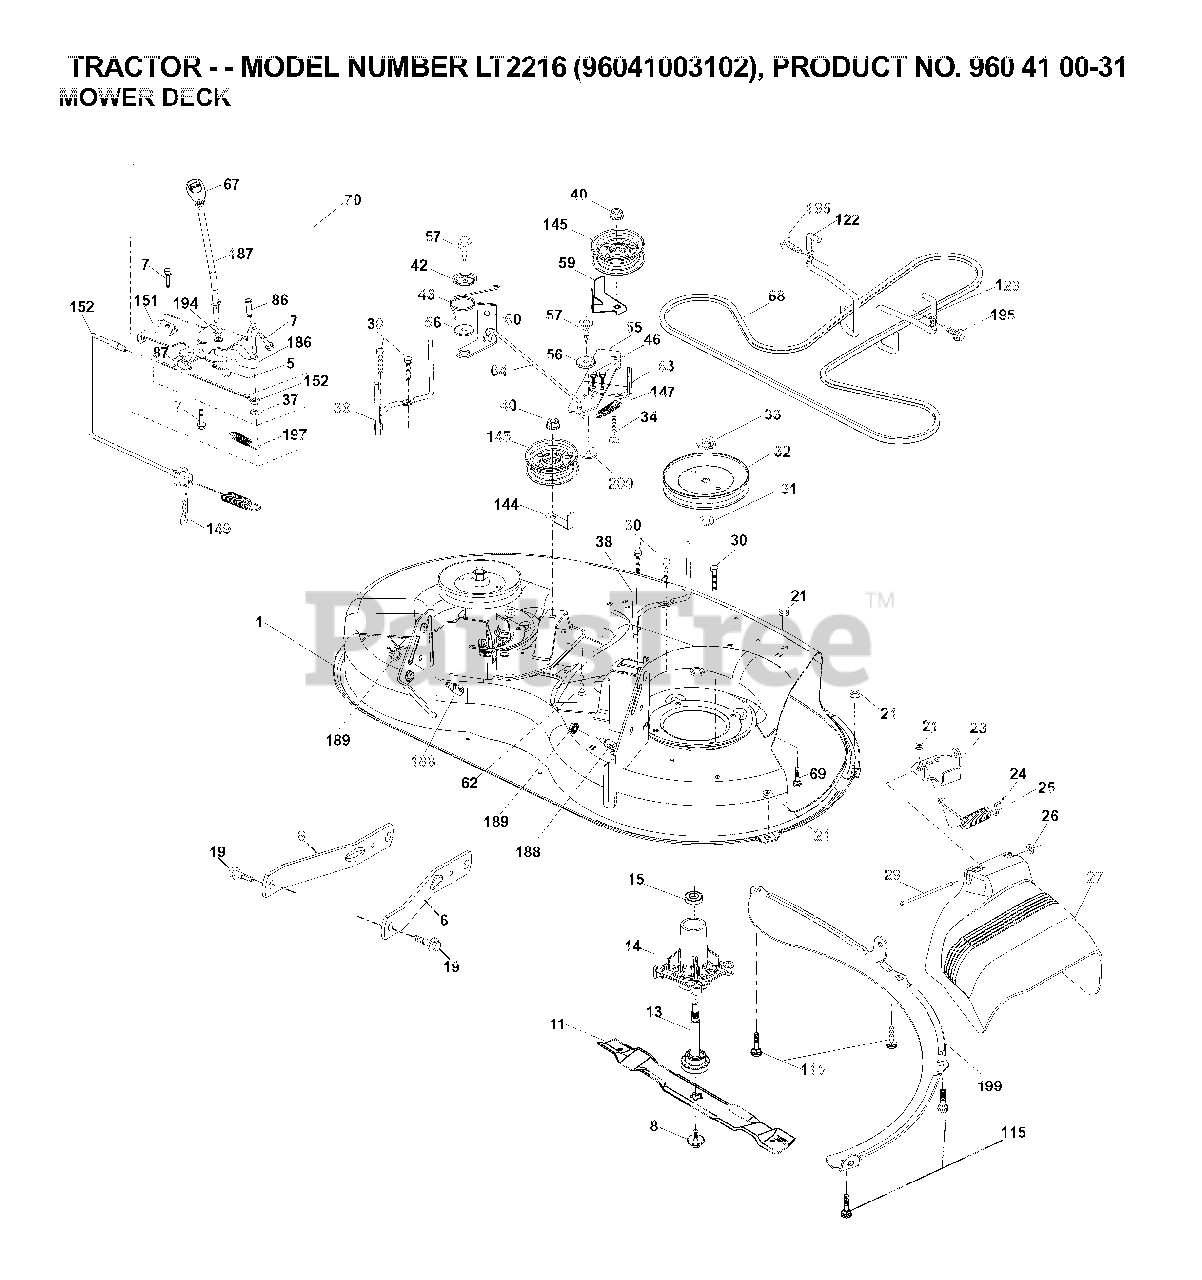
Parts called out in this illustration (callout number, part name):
6	ARM.SUSPENSION.MOWER.R
7	SCREW.#10 X 0.750.BOS THREAD
8	BOLT.WASHER.ASM.7/16-2
11	BLADE 38" PREMIUM
13	SHAFT.ASM.MDRL.N/GREASE.38
14	HOUSING MANDREL
19	BOLT.SHOULDER
21	LOCKNUT
23	BRKT.DEFLECTOR.38"2005+
24	CAP-SLEEVE LT
25	SPRING.TORSION.DEFLECT
26	NUT PUSH M
29	ROD.HINGE
30	SCREW, WASHER HEAD
31	WASHER.SPACER.MANDREL
32	PULLEY.MANDREL.5.0.PD.38"
33	NUT.FLANGE.LOCK.TOP
34	BOLT.3/8-16X1.50
38	KEEPER BELT LH MANDREL
40	NUT LOCK FLG 3/8-16 UNC
42	SPRING.TORSION.BRAKE
43	SRPING.TORSION.RETAINE
46	SCREW.1/4-20X5/8
55	IDLER.ARM
56	SPACER.RETAINER
57	SCREW 3/8-16X1
59	GUARD, BELT
60	ARM BRAKE MOWER RH 38"
62	BOLT.3/8-16X1.50
63	ARM BRAKE MOWER RH
64	LINK BRAKE
67	HANDLE.CLUTCH.CABLE.LT
69	BOLT
70	CLUTCH.ASM.MANUAL.LT.PRED
115	BOLT
122	KEEPER BELT ENGINE LH
123	KEEPER BELT RH
144	KEEPER, BELT IDLER
145	PULLEY.IDLER.48"PRIMARY
147	SPRING RETURN
149	SPRING.RETAINER.YELLOW.ZINC
152	CLUTCH CABLE
188	STUD.FASTNER.W/ANTI-ROTATE
189	NUT LOCK HEX FLANGE 5/16-18
195	SCREW, 3/8-16X3/4
199	BAFFLE VORTEX
209	WASHER 12/32X2X10GA
